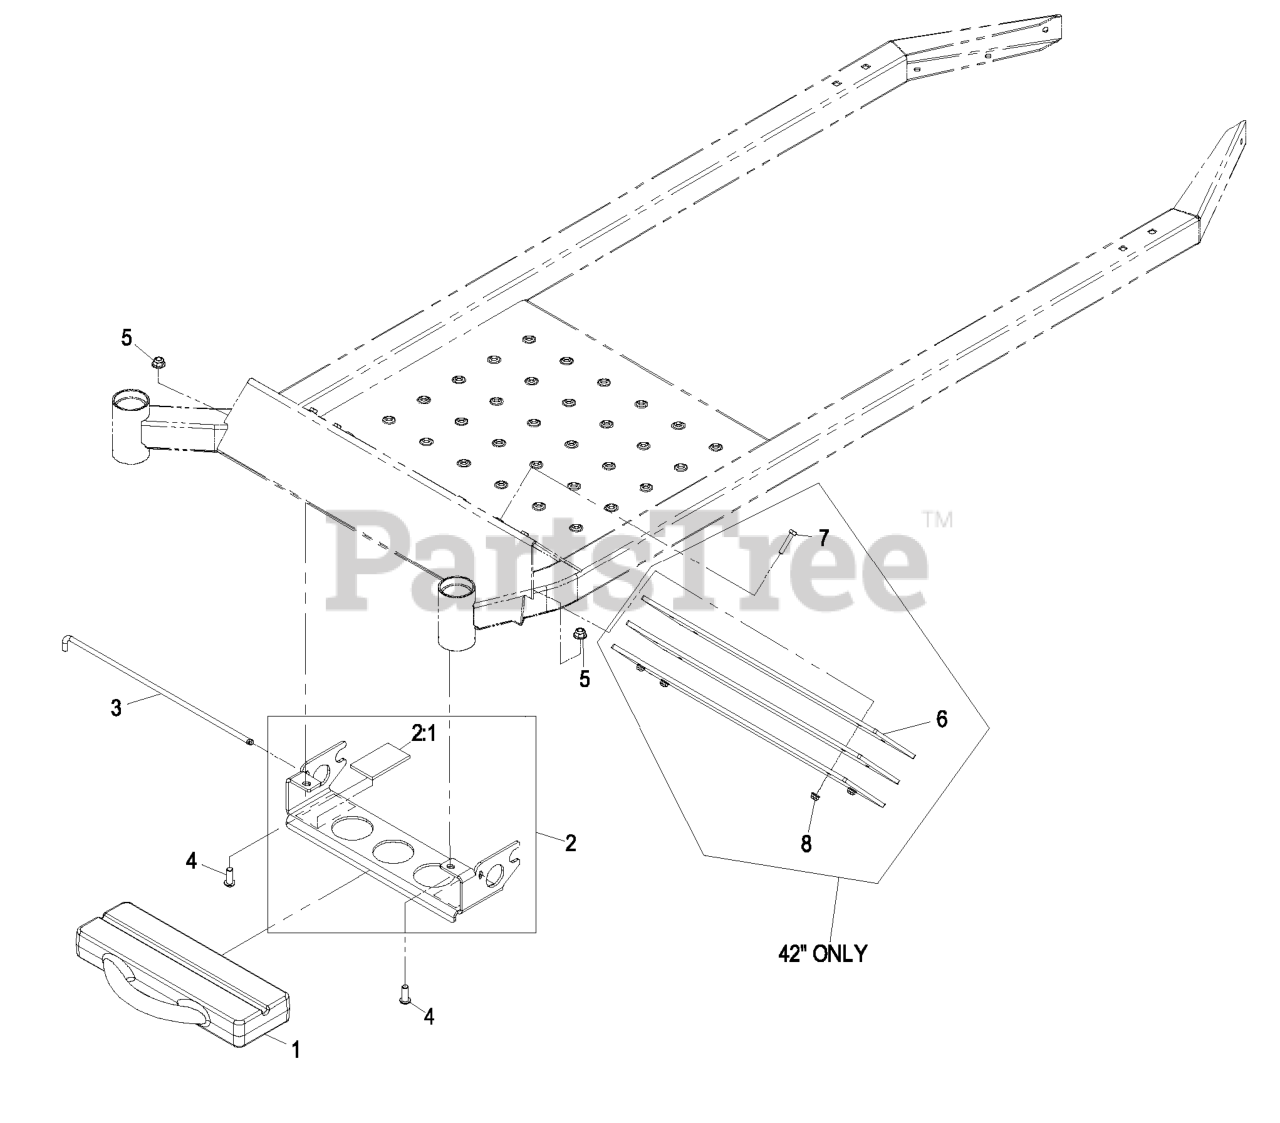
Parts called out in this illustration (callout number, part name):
2	BRACKET ASM
2:1	CUSHION-RUBBER
3	PIN-WEIGHT
4	SCREW-HSBH
5	NUT-HF, NI
6	WEIGHT,BAGGER
7	SCREW-HH
